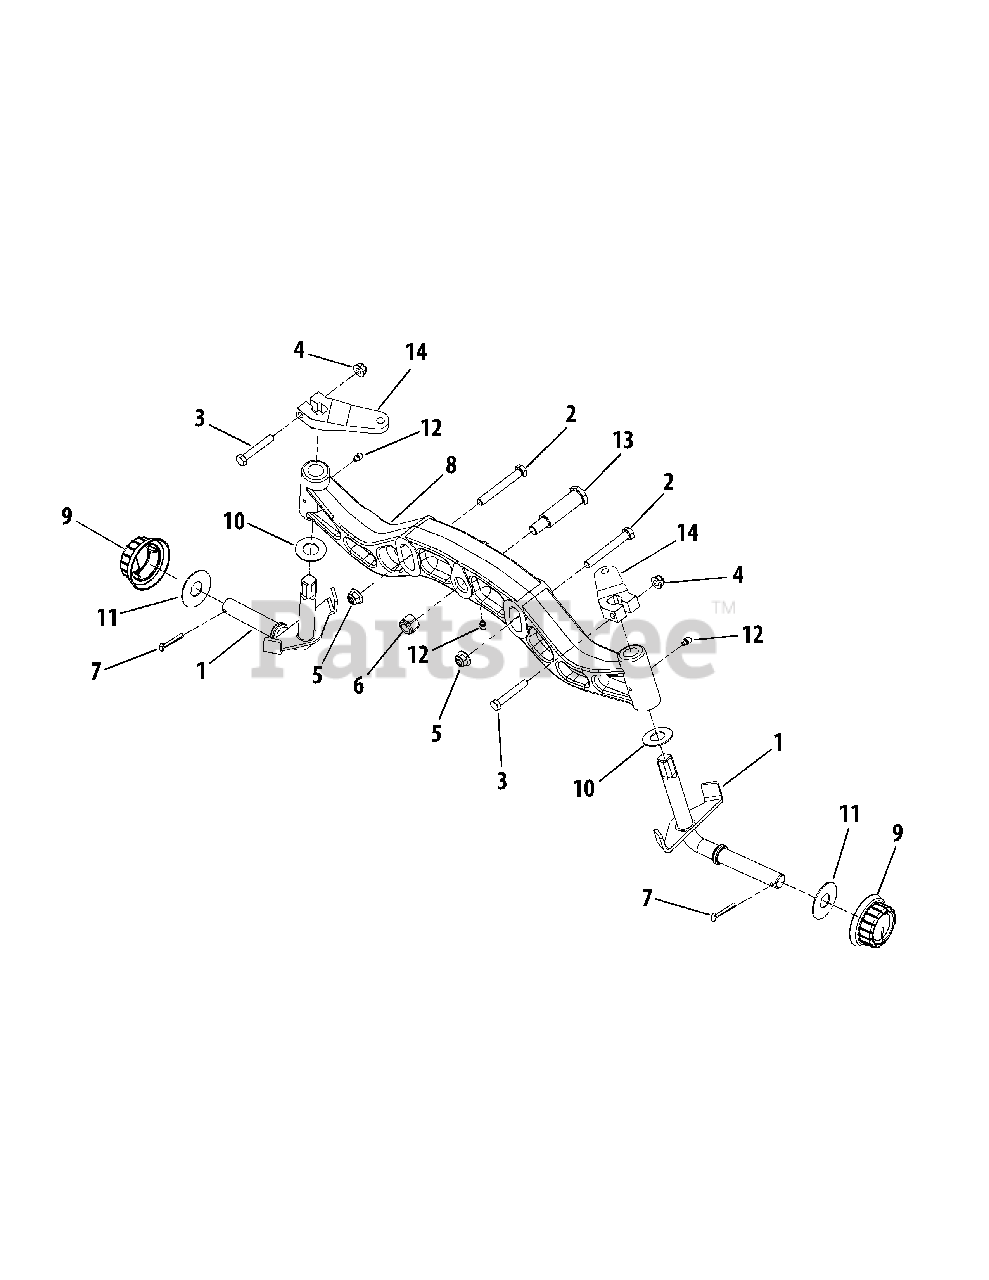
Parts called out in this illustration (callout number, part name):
1	Axle Assembly
2	Screw, Hex Cap, 3/8-16 x 2.75 GR8
3	Screw, Hex Cap, 5/16-18 x 2 GR5
4	Nut, Hex Flanged Lock, 3/8-16
5	Nut, Hex Flange Top Lock, 5/16-18
6	Nut, Hex Top Nylon Lock, 1/2-13
7	Pin, Cotter, 5/32 x 1.25
8	Axle, Front Pivot
10	Washer, Flat, .760 x 1.49 x .06 Thk.
11	Washer, Flat, .755 x 1.92 x .06
12	Fitting, Lube, 3/16 Drive Type
13	Bolt, Pivot Shoulder, 3/4 Dia x 2.23
14	Arm, Steering
